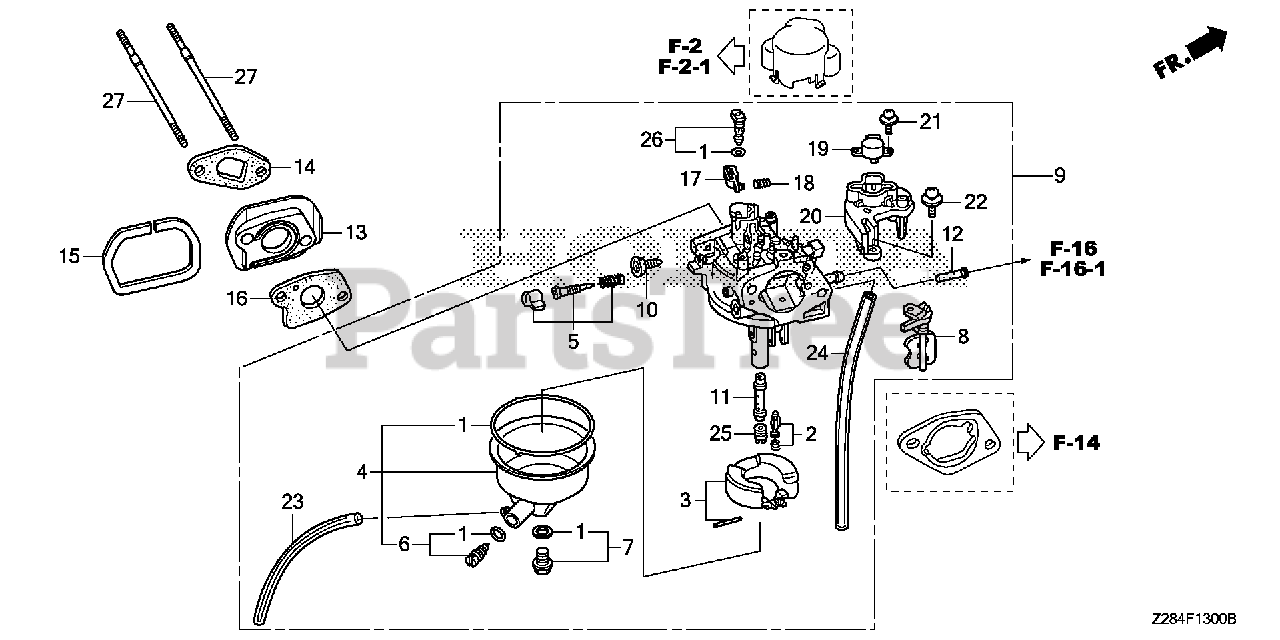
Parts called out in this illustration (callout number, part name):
1	GASKET SET
2	VALVE SET, FLOAT (CARBURETOR NO.) (SEAT NOT INCLUDED)
3	FLOAT SET
4	CHAMBER SET, FLOAT
5	SCREW SET (Honda Code 4219879). (CARBURETOR NO.)
6	SCREW SET, DRAIN (CARBURETOR NO.)
7	SCREW SET
8	CHOKE SET (CARBURETOR NO.)
9	CARBURETOR ASSY. (BE67S B)
10	SCREW, THROTTLE STOP
11	NOZZLE, MAIN
12	SCREEN, FUEL STRAINER
13	INSULATOR, CARBURETOR
14	GASKET, INSULATOR
15	SEAL, CARBURETOR INSULATOR
16	GASKET, CARBURETOR
17	LEVER, LINK (CARBURETOR NO.)
18	SPRING, COMPRESSION COIL (CARBURETOR NO.)
19	MOTOR, THROTTLE CONTROL
20	BRACKET, THROTTLE MOTOR
21	SCREW-WASHER (3X8)
22	SCREW-WASHER (4X10)
23	BULK HOSE, VINYL (3.5X6.5X8000) (9500(95003-05001-60M) (CARBURETOR NO.)
24	BULK HOSE, VINYL (4X7X8000) (95003-07(95003-07001-60M) (CARBURETOR NO.)
25	JET, MAIN (#72) (CARBURETOR NO.)
25	JET, MAIN (#75) (CARBURETOR NO.)
25	JET, MAIN (#78) (CARBURETOR NO.)
26	JET SET, PILOT (#45) (CARBURETOR NO.)
27	BOLT, STUD (6X108) (CT200)
